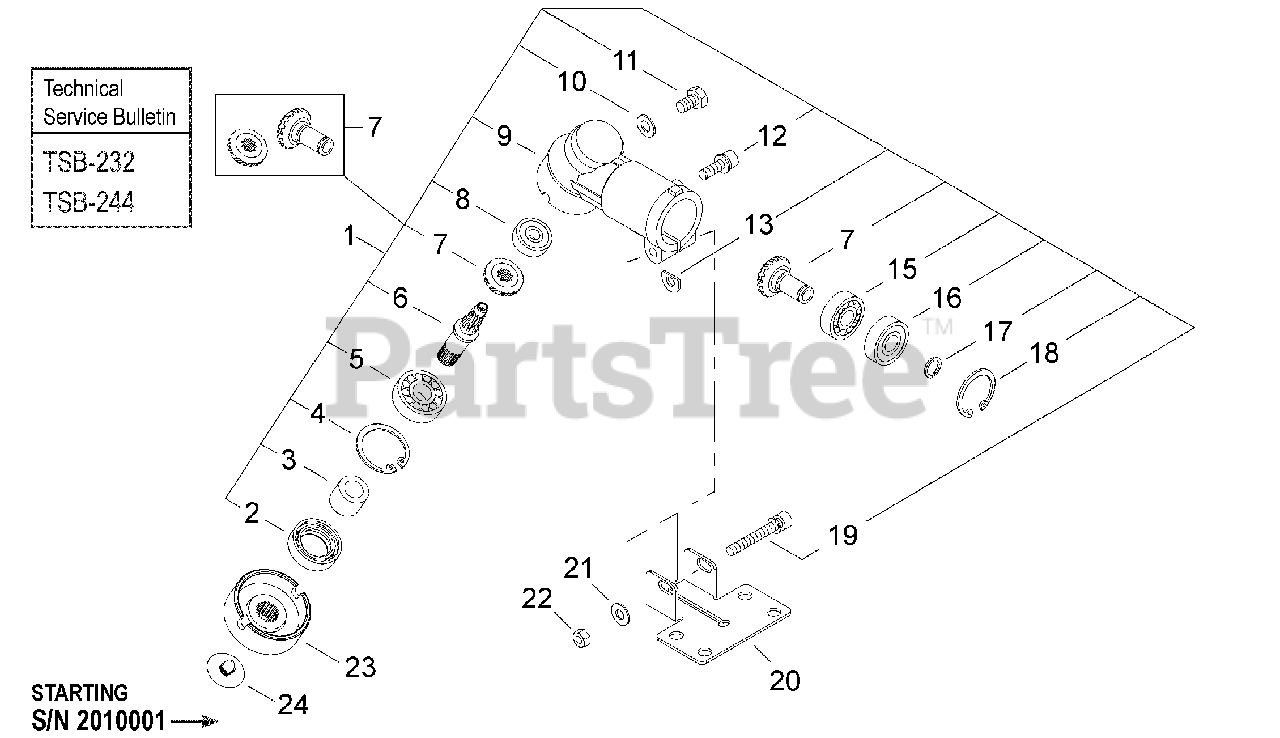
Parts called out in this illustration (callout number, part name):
1	GEAR CASE ASSY
2	SEAL, OIL
3	COLLAR
4	RING, RETAINING - 28
5	BEARING, BALL - 6001
6	GEAR - SHAFT
7	GEAR SET
8	BEARING, BALL - 608DDU
9	CASE, GEAR
10	WASHER - 6
11	BOLT - 6X10
12	SCREW - 5X16
13	SHIM
15	BEARING, BALL - 609
16	BEARING, BALL - 609ZZ
17	RING, RETAINING
18	RING, RETAINING - 24
19	SCREW - 5X35
20	CLAMP - LOWER
21	WASHER - 5
22	NUT - 5
23	HOLDER
24	CLAMP
